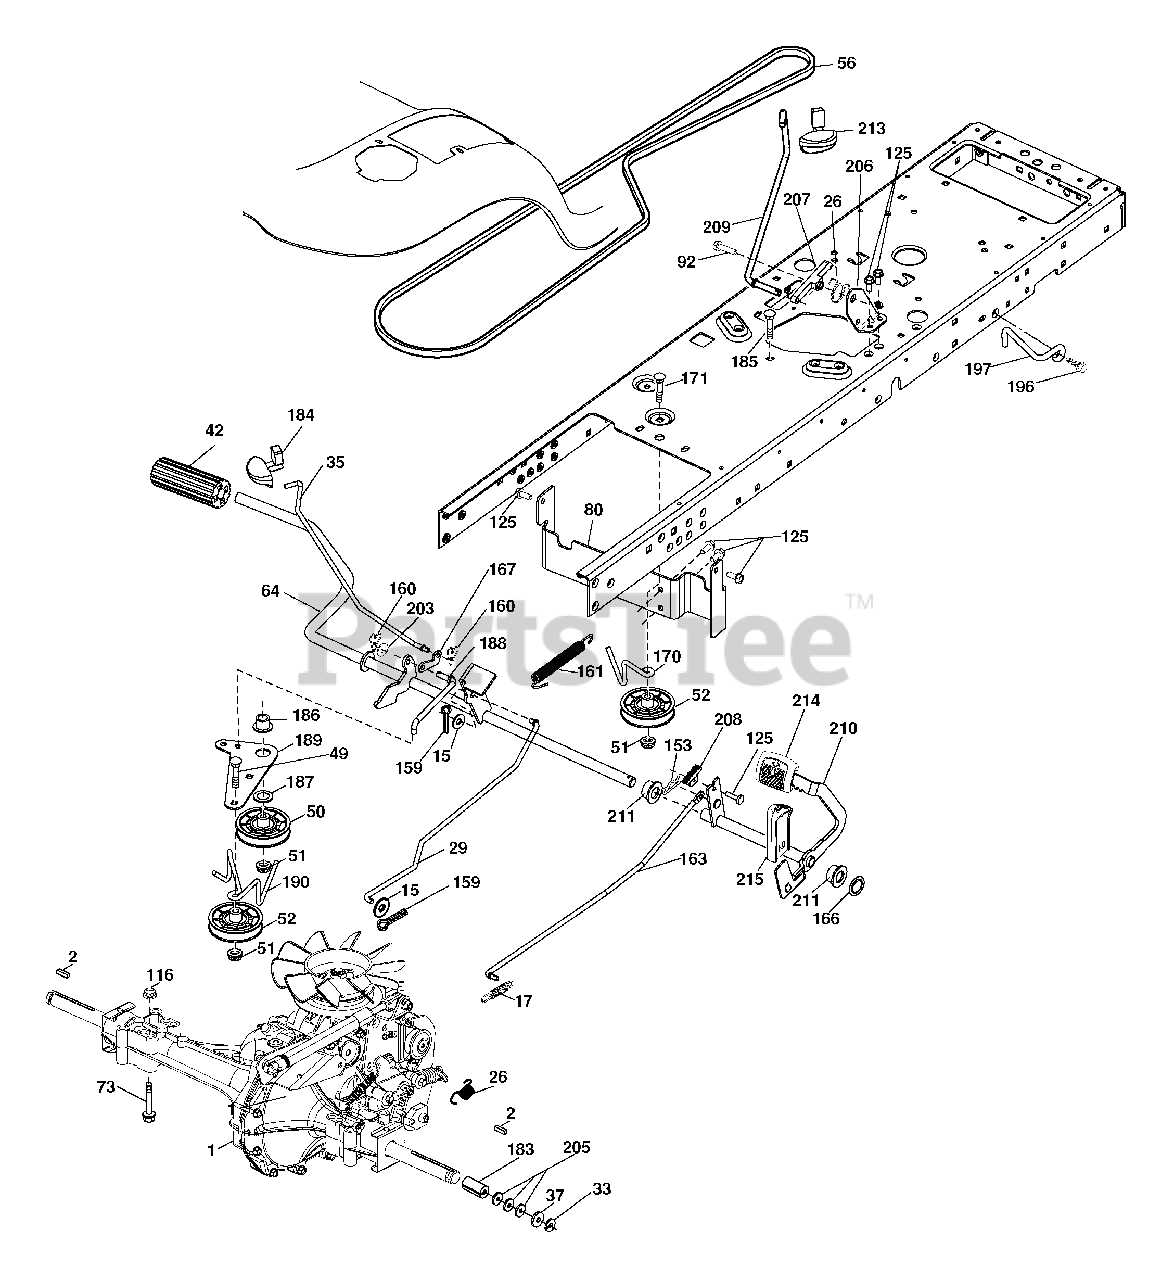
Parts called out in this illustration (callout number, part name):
2	Key
15	Washer 13/32 x 13/16 x 16 Ga.
17	Spring, Brake
29	Rod, Brake
33	Ring E
35	Rod, Brake, Park
37	Washer 25/32 x 1-1/4 x 16 Ga.
42	Cover, Foot Pedal
49	Bolt
50	Pulley Idler Flat
51	Lock Nut 3/8-16
52	Idler V-Groove 910" Offset
56	V-Belt, Drive
64	Shaft Asm. Pedal Brake Control
73	Bolt Hex Flghd 5/16-18 Gr. 5
80	Bracket Strap Torque
92	Bolt Fin Hex 5/16-18 unc x 1.25
116	Nut Lock Hex Flange 5/16-18
125	Screw 5/16-18 x 3/4
153	Retainer Spring
159	Pin Cotter 1/8 x 3/4
160	Retainer Clip
161	Spring, Return, Clutch
163	Rod Pedal Control
166	Nut Push .625
167	Latch Brake Parking
170	Keeper Belt Centerspan
171	Bolt
183	Spacer Axle
184	Handle Parking Brake
185	Bolt
186	Spacer Retainer
187	Washer
188	Link Clutch Ground Drive
189	Bellcrank Ground Drive
190	Keeper Bellcrank Ground Drive
196	Screw 3/8-16 x 1
197	Link Clutch Anti Rotation
203	Washer 11/32 x 11/16 x 16 Ga.
205	Washer 25/32 x 1-5/8 x 16 Ga.
206	Bracket Mount Latch Cruise
207	Latch Control Cruise
208	Gear Sector Control Cruise
209	Rod Control Cruise
210	Rockr Asm. Pdeal Control
211	Bearing Nylon
213	Knob control Cruise
214	Pad Pedal Forward
215	Pad Pedal Reverse
